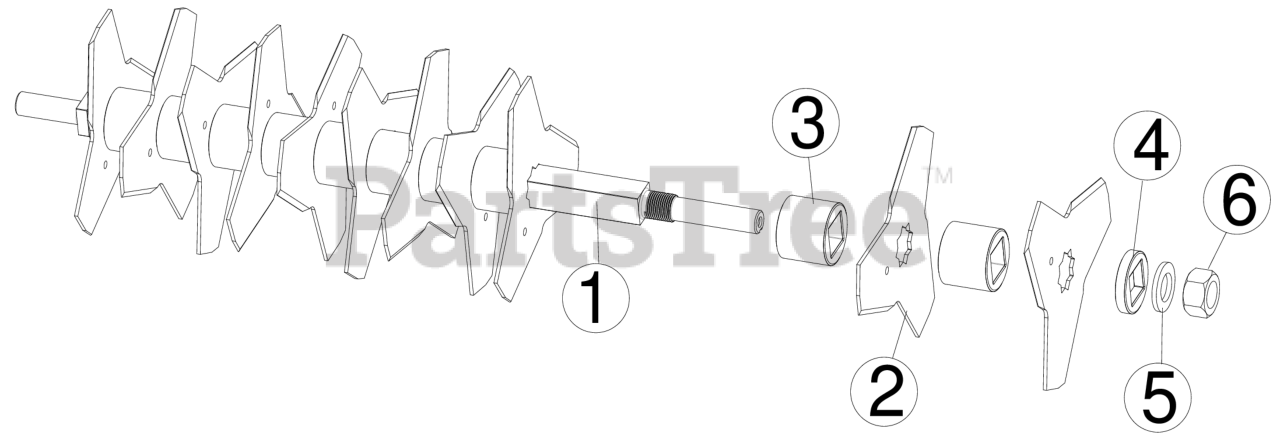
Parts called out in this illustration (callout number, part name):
1	SHAFT VERTICUTTING REEL OSSP
2	BLADE, VERTICUT LASER CLAD
3	SPACER, PM REEL OS900SP
4	SPACER HARDENED REEL
5	SPRING DISC 7/8" ID
6	NUT 7/8-14 NC
